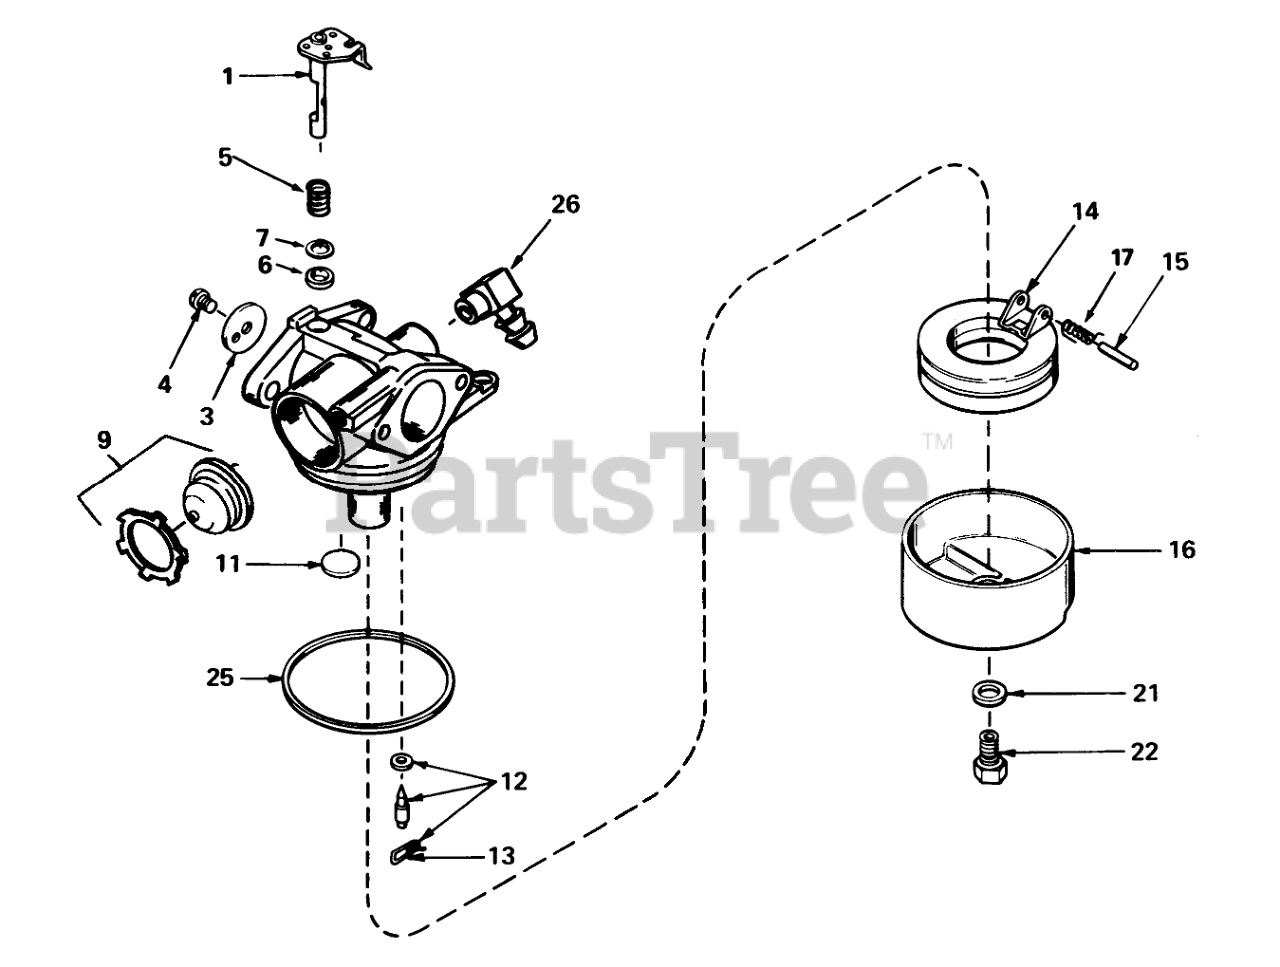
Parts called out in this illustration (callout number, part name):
1	Throttle Shaft and Lever ASM
3	Shutter-Throttle
4	Screw-Shutter
5	Spring-Return, Throttle
6	Seal-Dust
7	Washer-Seal, Dust
9	Bulb-Primer
11	Plug-Welch, Atmospheric Vent
12	Needle Seat & Clip Assy. (Incl. Ref. #13)
13	Clip-Spring
14	Float
15	Shaft-Float
16	Bowl-Float (no drain)
17	Spring-Float, Dampening
21	Washer-Bowl Nut
22	Nut-Float Bowl
25	O Ring-Bowl, Float
26	Fitting-Fuel
